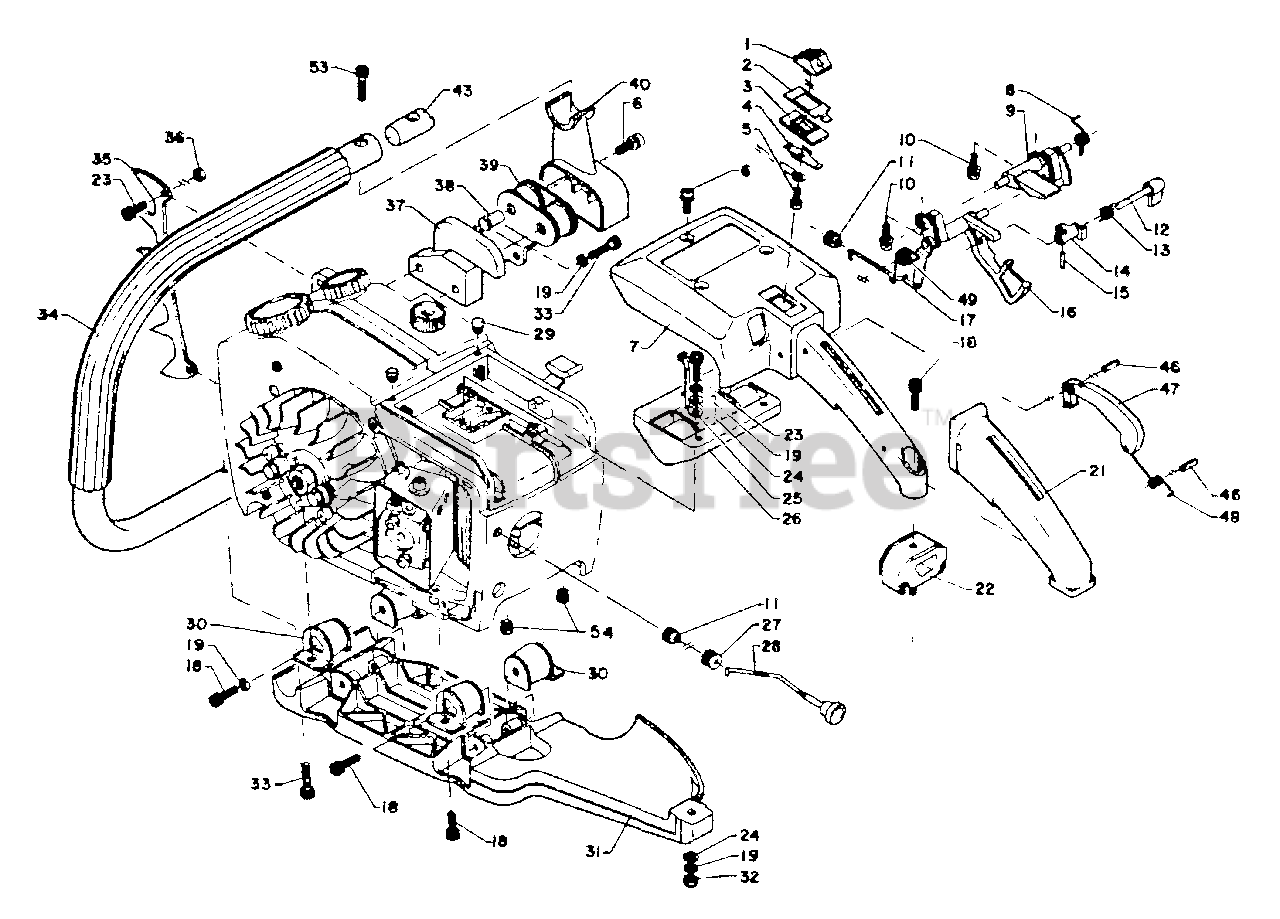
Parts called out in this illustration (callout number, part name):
1	KNOB, SWITCH
2	PLATE - GROUND
3	GUIDE, SWITCH
4	CONTACT, SWITCH
5	SCREW - 4X10
6	SCREW - 5X14
7	HANDLE - REAR
9	Push lever
10	SCREW - 4X14
11	GROMMET
12	LEVER, THROTTLE
13	SPRING, LOCKOUT LEVER
14	LOCKOUT, THROTTLE
15	PIN - SPRING -- 1.6X10
16	TRIGGER, THROTTLE
17	ROD, THROTTLE
18	SCREW - 5X15
19	LOCKWASHER - 5
21	COVER, HANDLE
22	CUSHION
23	SCREW - 5X12
24	WASHER - 5
25	LEAD - GROUND
26	CUSHION
28	ROD, CHOKE
29	CUSHION
30	CUSHION
31	BRACKET, HANDLE - LOWER
33	SCREW - 5X20
34	HANDLE - FRONT
35	SPIKE
36	LOCKNUT - 5
37	Cushion rubber holder
39	Cushion rubber (L-U)
40	BRACKET, HANDLE - UPPER
46	PIN - SPRING -- 4X16
47	LOCKOUT, THROTTLE
48	SPRING, LOCKOUT LEVER
49	SPRING, TRIGGER
53	SCREW - 5X25
